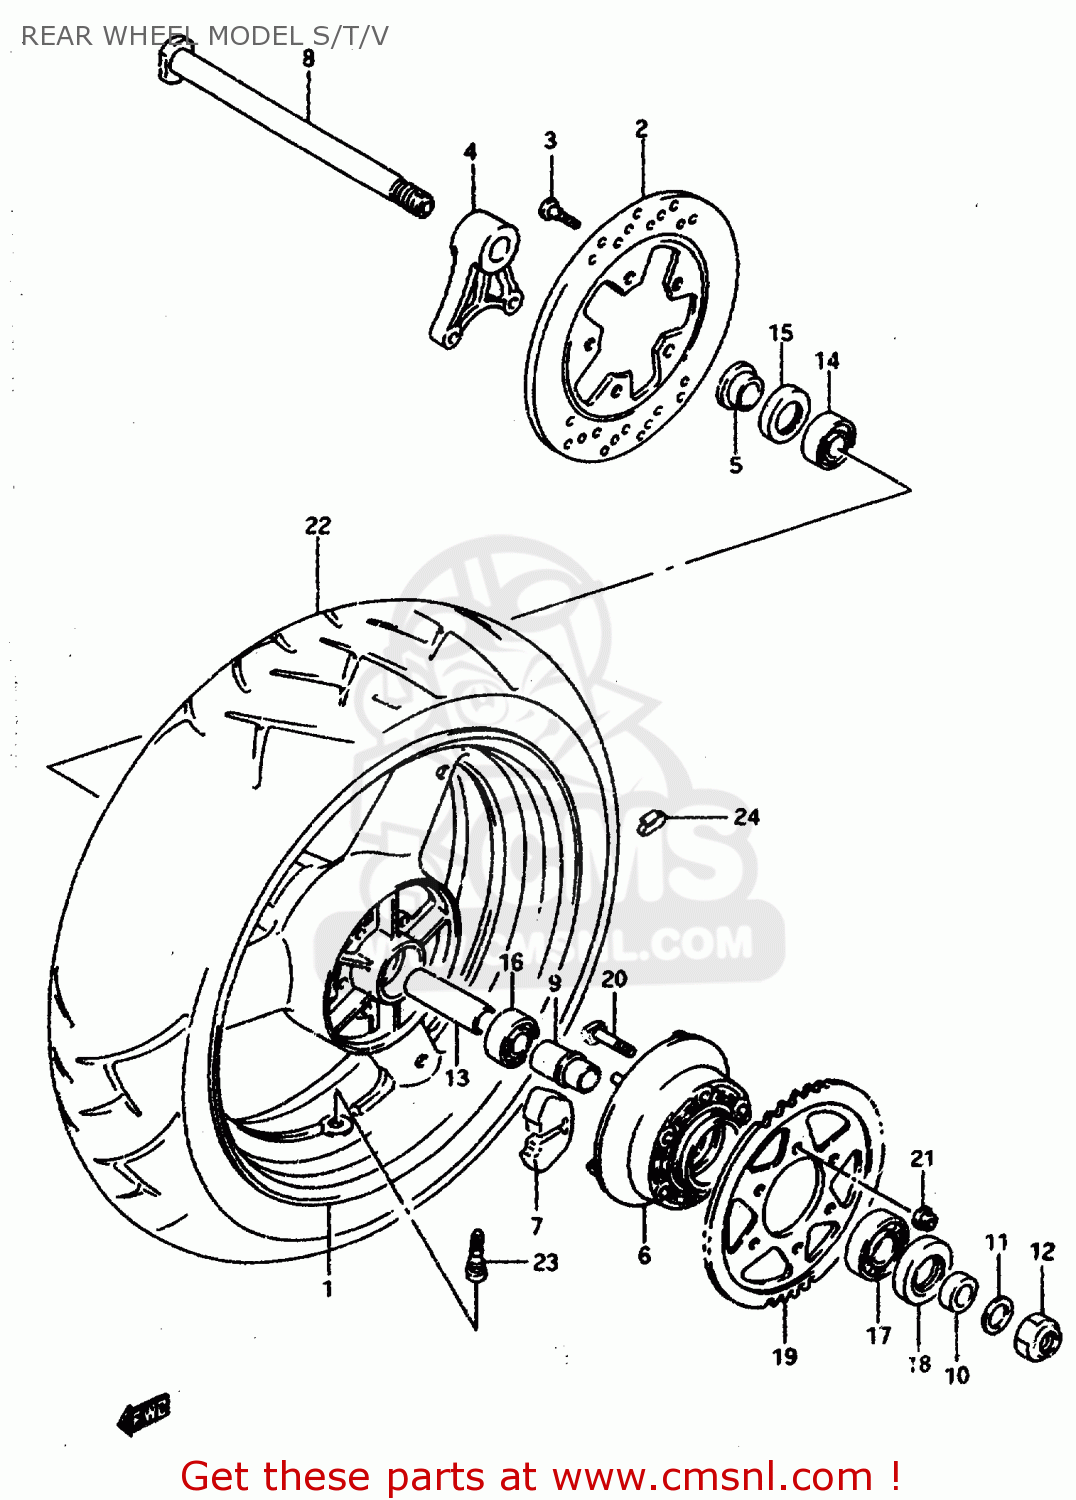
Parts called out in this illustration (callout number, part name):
1	WHEEL,REAR
2	DISC,RR BRAKE
3	BOLT 8X33
4	BRACKET,RR CALIPER
5	SPACER,RR AXLE,R
6	DRUM,RR SPROCKET
7	ABSORBER,RR HUB SHOCK
8	AXLE,RR
9	RETAINER,RR HUB BEARING
10	SPACER,RR AXLE,L
11	WASHER (18.2X28X2.6)
12	NUT
13	SPACER,RR WHEEL HUB BEARING
14	BEARING(20X47X14)
15	SEAL,OIL(28X47X7)
16	BEARING(20X47X14)
17	BEARING(25X62X17)
18	SEAL,OIL(35X62X8)
19	SPROCKET,RR(NT:44-532)
20	BOLT
21	NUT
22	TIRE,REAR 180/55 ZR17
23	VALVE ASSEMBLY,WHEEL,TR412
24	BALANCER,WHEEL (10G)
26	VALVE ASSEMBLY,WHEEL,TR412
27	BALANCER,WHEEL
